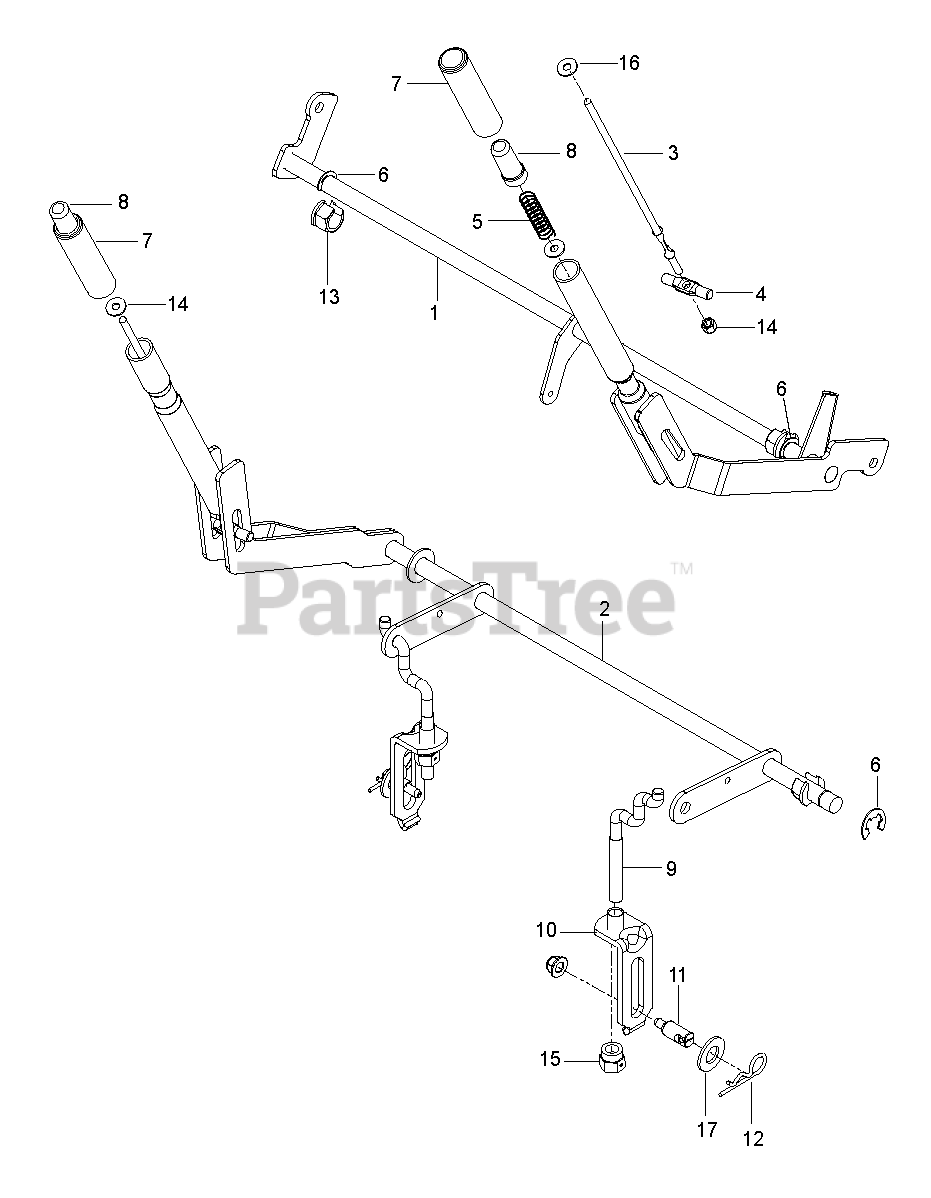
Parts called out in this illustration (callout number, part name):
1	BRAKE LEVER ASSY WLDMT MED MS
2	DECK.LIFT.PNT.WELDMENT.RZ.BLK
3	ROD, HANDLE RELEASE
4	ROD LATCH RELEASE
5	SPRING, COMPRESSION
6	E Ring #5133-62 (AYP part number)
7	GRIP, HANDLE, BLACK
8	BUTTON, PUSH, BLACK (2 2)
9	LINK, REAR SUSPENSION
10	ASSEMBLY, BRKT LINK
11	STUD.FASTNER.W/ANTI-ROTATE
12	HAIRPIN #4
13	PLASTIC NUT
14	NUT 1/4-20 NYLOC
15	NUT, LIFT LINK 7/16-20
16	Washer 9/32 x 3/4 x 16 Gauge (AYP part number)
17	WASHER
